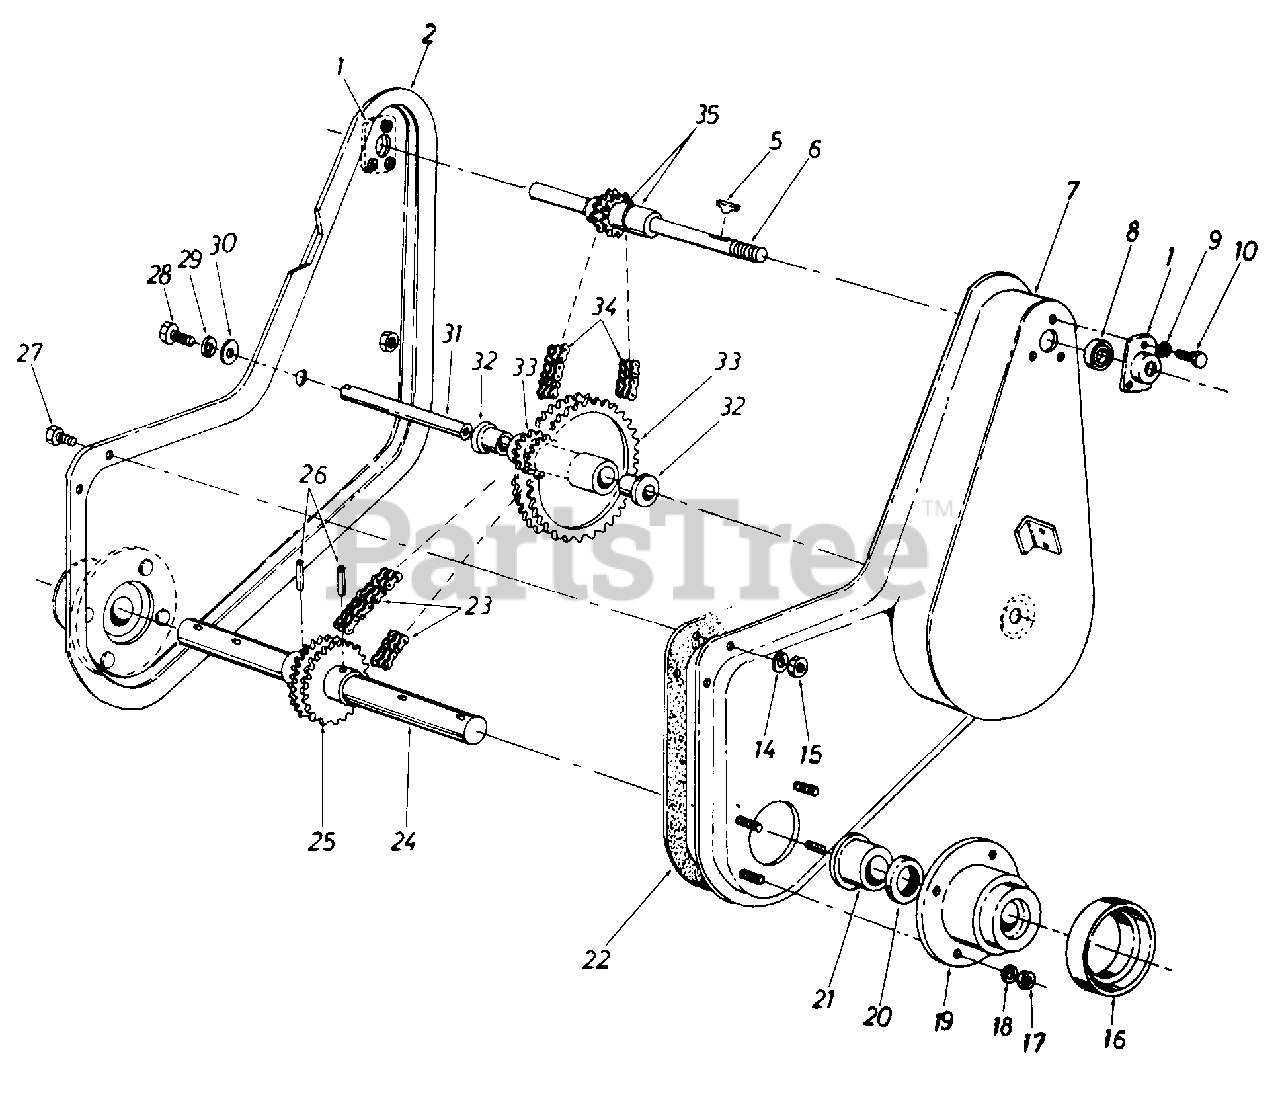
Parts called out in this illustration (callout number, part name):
1	Bearing Housing 1.375" Dia.
6	Input Shaft Assembly
9	L-Wash. 1/4" I.D.
10	Hex Bolt 1/4-20 x .62" Lg.
14	L-Wash. 1/4" I.D.
15	Hex Cent. L-Nut 1/4-20 Thd.
16	Dust Cap Cover
17	Hex Cent. L-Nut 5/16-18 Thd.
18	L-Wash. 5/16" I.D.
19	Cast Bearing Housing
20	Oil Seal
21	Flange Bearing 1.25" I.D. x 1.75" O.D.
22	Gasket
23	Roller Chain #402 x 34.0 Lg.
24	Tine Shaft
25	Double Sprocket T24-2 Teeth 1/2" Pitch
26	Spiral Pin 3/8 Dia. x 2.00 Lg.
27	Hex Bolt 1/4-20 x .62 Lg.
28	Hex Bolt 5/16-18 x .75 Lg.
29	L-Wash. 5/16" I.D.
30	Fl-Wash. 5.16 I.D.
31	Sprocket Shaft
32	Flange Bearing .62 I.D. x .75" O.D.
33	Double Sprocket Assembly
34	Roller Chain #35-2 x 36.75 Lg.
35	Spacer 5/8 I.D. x 7/8 O.D.
